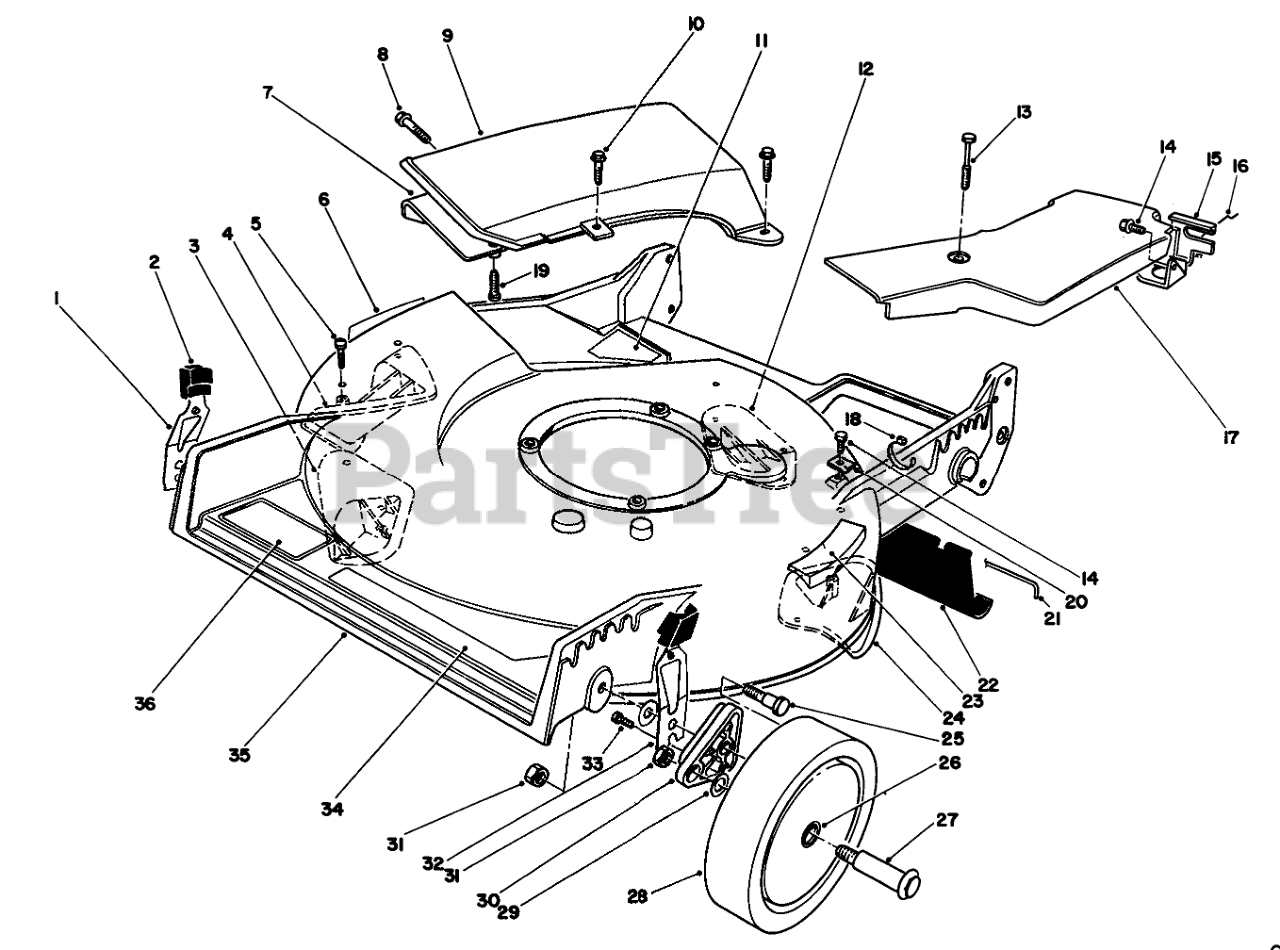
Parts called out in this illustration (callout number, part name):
1	RH SPRING ARM ASSEMBLY
2	KNOB-ARM
3	KICKER
4	KICKER
5	SCREW-PPH
6	DECAL-DANGER
7	Deflector-Recycler
8	SCREW AND WASHER ASM
9	Cover Assembly (Incl. Ref #7 & 19)
10	SCREW-HWH
11	DECAL - DANGER
12	KICKER
13	SCREW-HHFTF
14	SCREW-HWHTF
15	Bracket-Adj. Trac
16	RETAINER-CABLE
17	BELT COVER
18	TIE-CABLE
19	Screw-Pan Hd.
20	CLAMP-CABLE
21	ROD-SHIELD
22	SHIELD-TRAILING
23	STEP PAD DECAL
24	KICKER
25	SCREW-SHOULDER
26	BUSHING
27	WHEEL BOLT
28	Wheel & Tire Assembly (Incl. Ref. #26)
29	WASHER
30	ARM-PIVOT, FRONT
31	Nut
32	LH SPRING ARM ASSEMBLY
33	SCREW-HWH
34	DECAL - DECK
35	Housing (Incl. Ref. #3-6, 12, & 24)
36	DECAL
